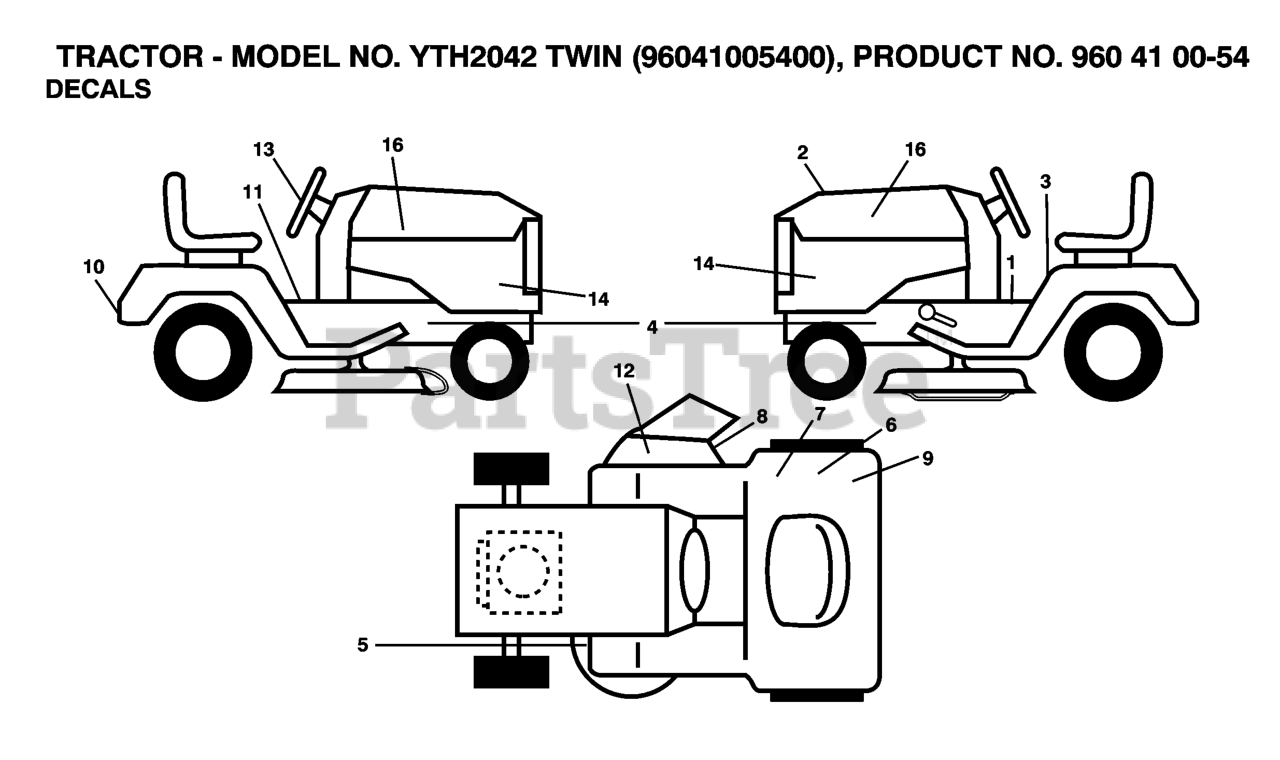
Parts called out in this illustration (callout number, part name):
1	DECAL PARK BRAKE
2	DECAL.HOOD.TOP.INSERT.
3	LABEL
5	DECAL V BELT SCHEMATIC
6	DECAL
7	DECAL 80 DBA
8	DECAL, DEFLECT WARNING
9	DECAL
10	DECAL
11	DECAL
12	DECAL.INTERNATIONL.CUTFINGER
13	DECAL.WHEEL.STRG.LGN.H
16	DECAL.HOOD.NAMELOGO.HUSQ
